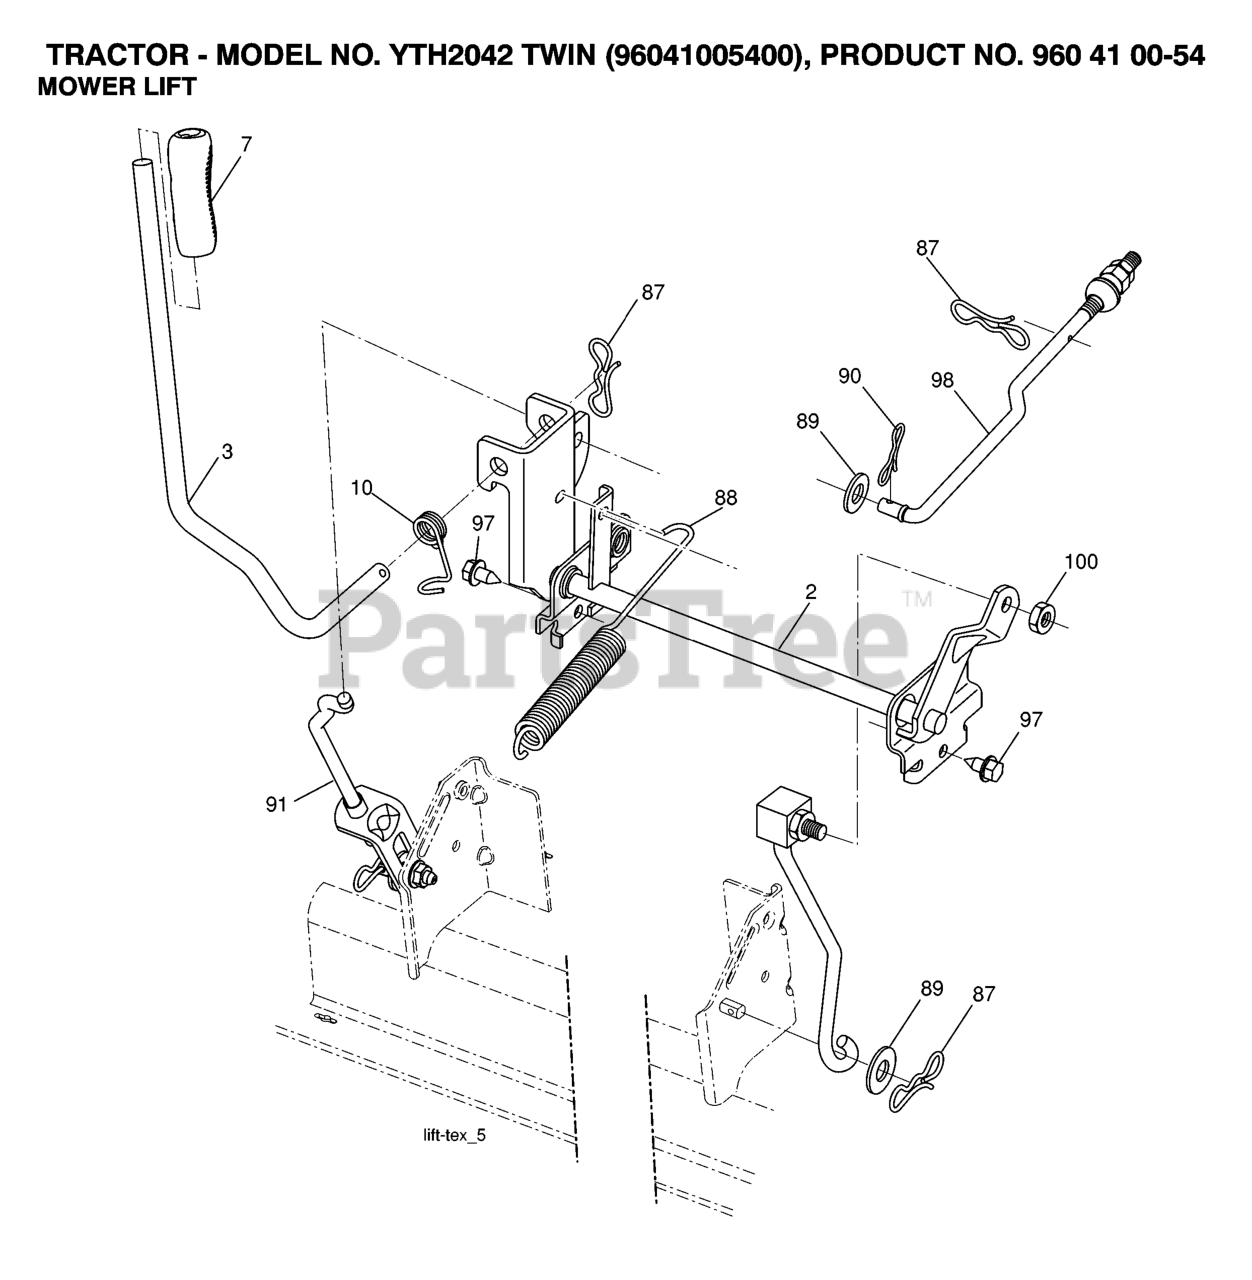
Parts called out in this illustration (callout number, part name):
2	SHAFT.ASM.LIFT.CROSS.H
3	LEVER.LIFT.HANDLE.GT
7	GRIP.LEVER.5625.ID
10	SPRING.TORSION.LIFT.HANDLE
87	PIN.COTTER.7/16.BOW TI.
88	SPRING.LIFT.ASSIST.GT2
89	WASHER.CLEAR.ZINC
90	PIN.COTTER.5/16.BOW TI
91	LINK.ASM.LIFT.REAR
97	SCREW 3/8-16X3/4
98	LINK.ASM.SUSP.FRONT.MW
100	LOCKNUT
